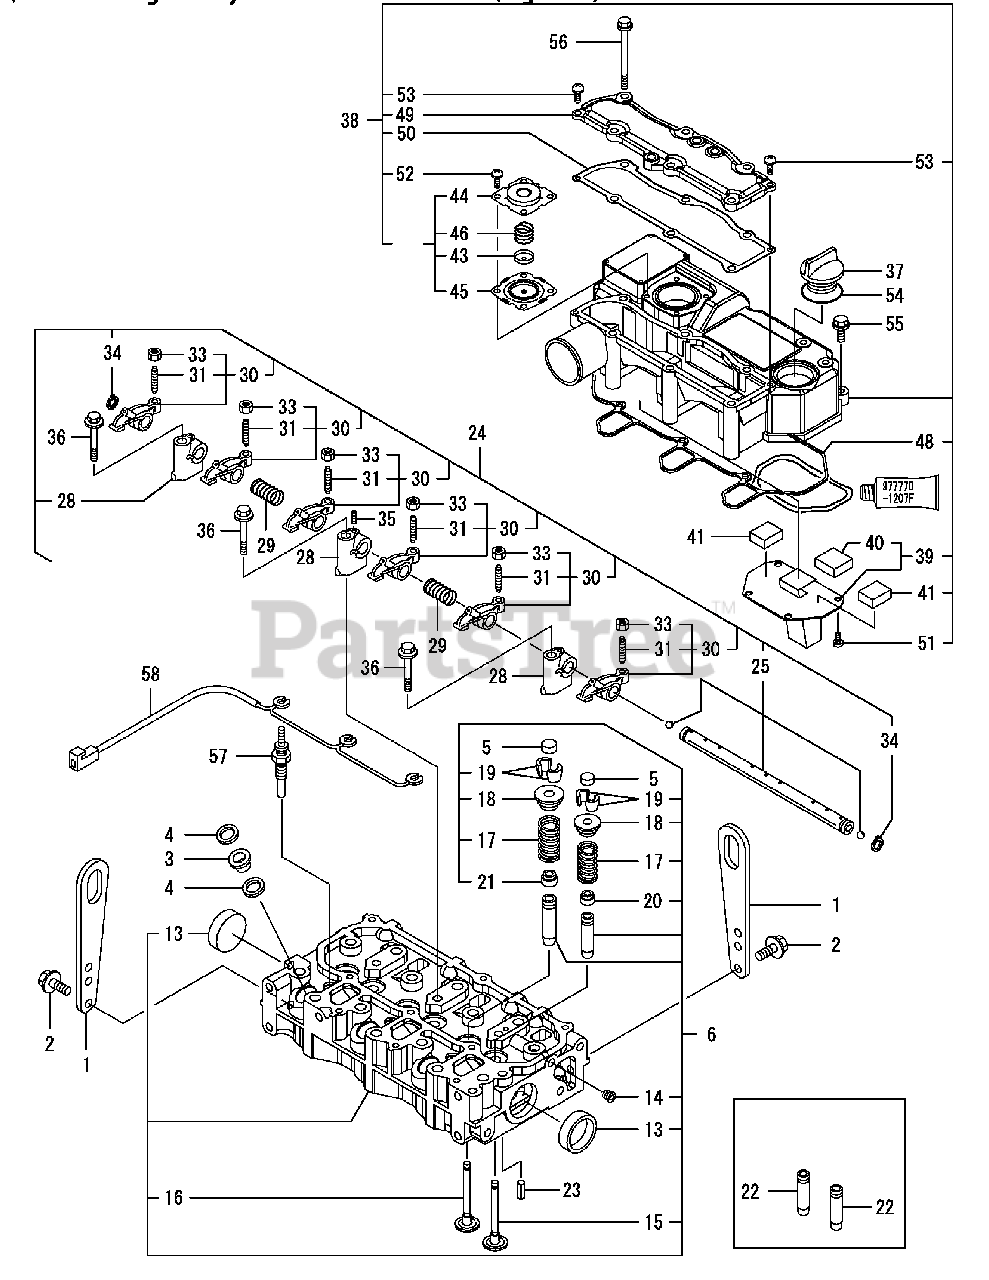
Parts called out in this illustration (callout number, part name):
1	Lifter, Engine
2	Bolt, M 8 x 16 Plated
3	Protector, Nozzle
4	Gasket, Nozzle
6	Head Assembly, Cylinder
14	Plug Pt, 1/16, Screw
16	Valve, Exhaust
18	Retainer, Spring
20	Seal, Valve Stem
21	Seal, Valve Stem
23	Spring Pin, 6 x 12
24	Support Assembly, Arm
25	Shaft Assembly, Rocker
28	Support, Rocker Arm
30	Arm Assembly, Rocker
33	Nut, M8 x P1.0
35	Screw, M 5 x 16
36	Bolt, M8 x 40 Plated
38	Bonnet Assembly, Head
40	Baffle, Breather
41	Baffle, Breather
43	Plate, Diaphragm
44	Cover, Diaphragm
46	Spring, Diaphragm
48	Gasket, Bonnet
50	Gasket, Bonnet Cover
51	Screw, 5 x 10, Tapping
52	Screw, 5 x 10, Tapping
54	O-Ring, 1A P-32.0
55	Bolt, M 6 x 20 Plated
56	Bolt, M 6 x 75 Plated
57	Plug, Glow
58	Connector, Glow Plug
